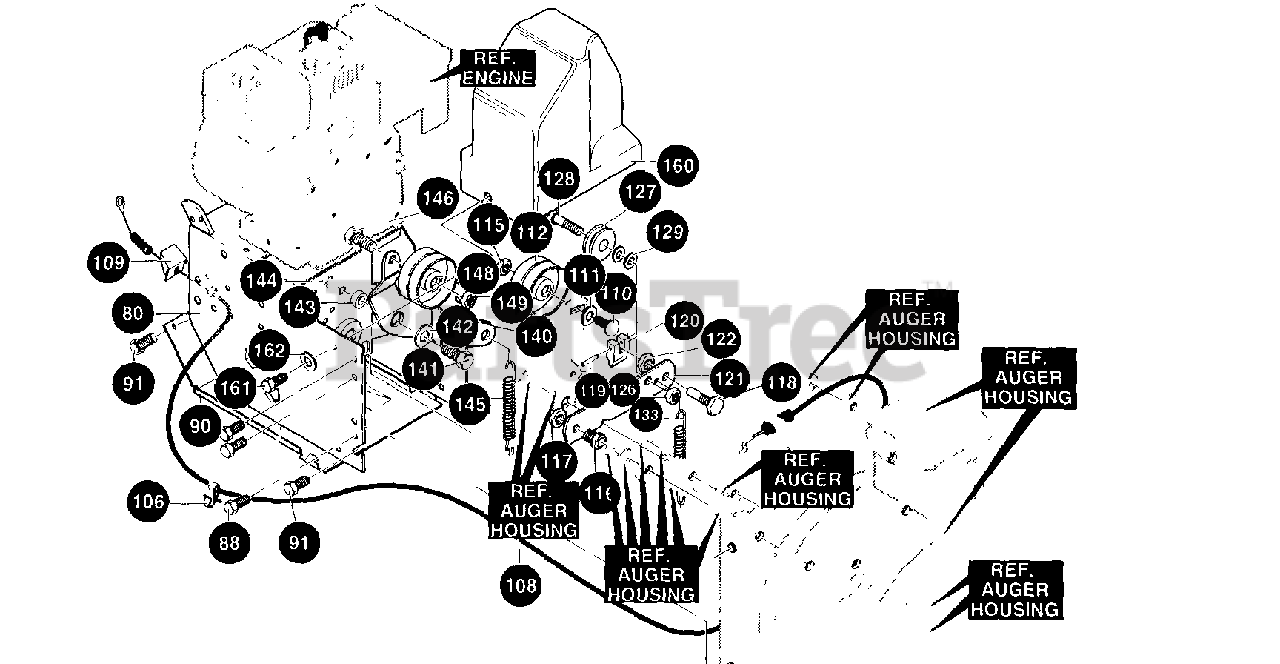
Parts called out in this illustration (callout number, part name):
80	FRAME, ASSY
88	SCREW, 5/16-18X .50
90	COVER, BOTTOM
91	SCREW, 1/4-20X .63
106	CLIP, CABLE TINN
108	CABLE, AUGER
109	SHIELD, CABLE GUARD
110	CARR BOLT 3/8-16X1/2
111	FLATWASHER
112	PULLEY, IDLER
115	NUT, 3/8-16
116	BOLT, BRAKE ARM
117	NUT, 9/16-18 JAMCTRLK
118	BOLT, BRAKE ARM ADJ
119	SPRING PIN
120	PAD, AUGER/IMP
121	BRACKET,PUCK
122	NUT, 1/2-20 JAMCTRLK
126	NUT, 1/4-20
127	PULLEY, METAL
128	BOLT, SH 1/4-20
129	FLATWASHER
133	SPRING, IDLER BRAKE
140	LEVER, IDLER ARM TRACTION
141	SCREW, 5/16-18X .75
142	FLATWASHER, .328 X 1.25 X .075
143	BUSHING, IDLER LEVER
144	NUT, 5/16-18 MEXNYL
145	IDLER SPRING
146	SCREW, 3/8-16 X 1.25
148	PULLEY, IDLER
149	NUT, 3/8-16
160	COVER, BELT
161	SCREW, 1/4-20X 63
162	FLATWASHER, .281 X .63 X .065
